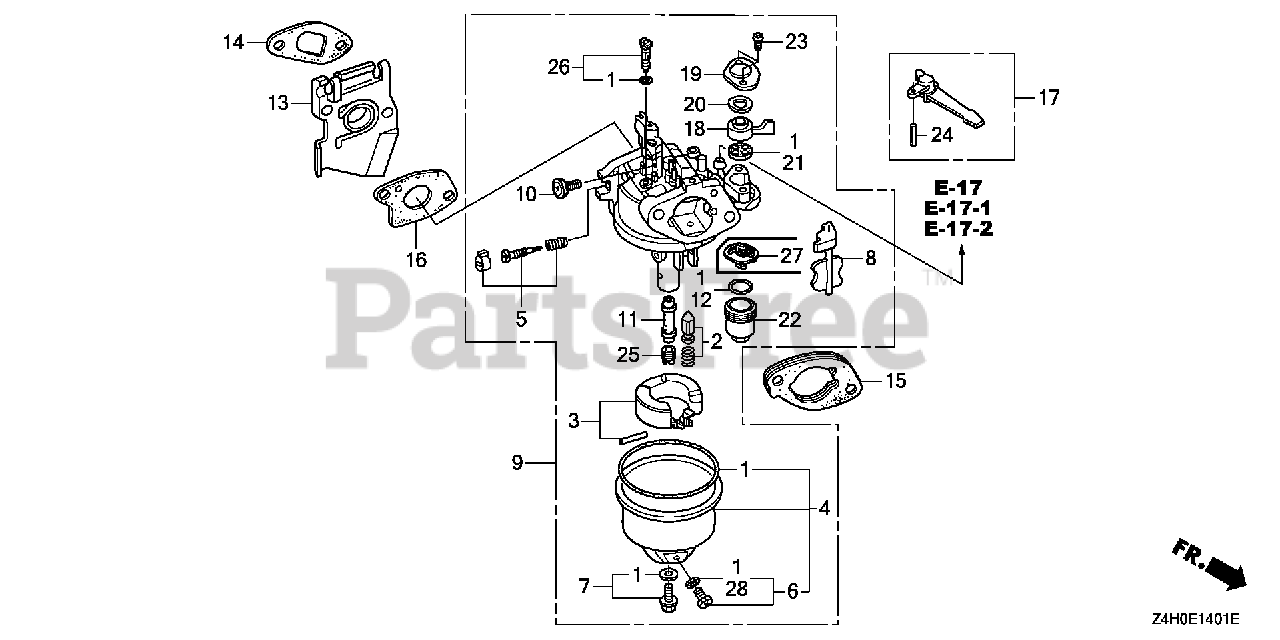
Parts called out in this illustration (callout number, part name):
1	GASKET SET
2	VALVE SET, FLOAT (CARBURETOR NO.) (SEAT NOT INCLUDED)
3	FLOAT SET
4	CHAMBER SET, FLOAT (CARBURETOR NO.)
5	SCREW SET (Honda Code 4219879). (CARBURETOR NO.)
6	SCREW SET, DRAIN (Honda Code 1672187). (CARBURETOR NO.)
7	SCREW SET
8	CHOKE SET
9	CARBURETOR ASSY. (BE60R A)
10	SCREW, THROTTLE STOP
11	NOZZLE, MAIN
12	GASKET, FUEL STRAINER CUP
13	INSULATOR, CARBURETOR
14	GASKET, INSULATOR
15	SPACER, CARBURETOR
16	GASKET, CARBURETOR
17	LEVER, CHOKE (STD)
18	LEVER, VALVE
19	PLATE, LEVER SETTING (CARBURETOR NO.)
20	SPRING, PETCOCK LEVER (CARBURETOR NO.)
21	GASKET, VALVE
22	CUP, FUEL STRAINER
23	SCREW, PAN (3X6)
24	PIN, SPRING (2X12)
25	JET, MAIN (#55) (CARBURETOR NO.) Use up to Engine SN BE03A J.
25	JET, MAIN (#58) Use from Engine SN BE30B E.
25	JET, MAIN (#60)
26	JET SET, PILOT (#35)
28	WASHER, PLAIN (6.2X10.7 DRAIN) (CARBURETOR NO.)
